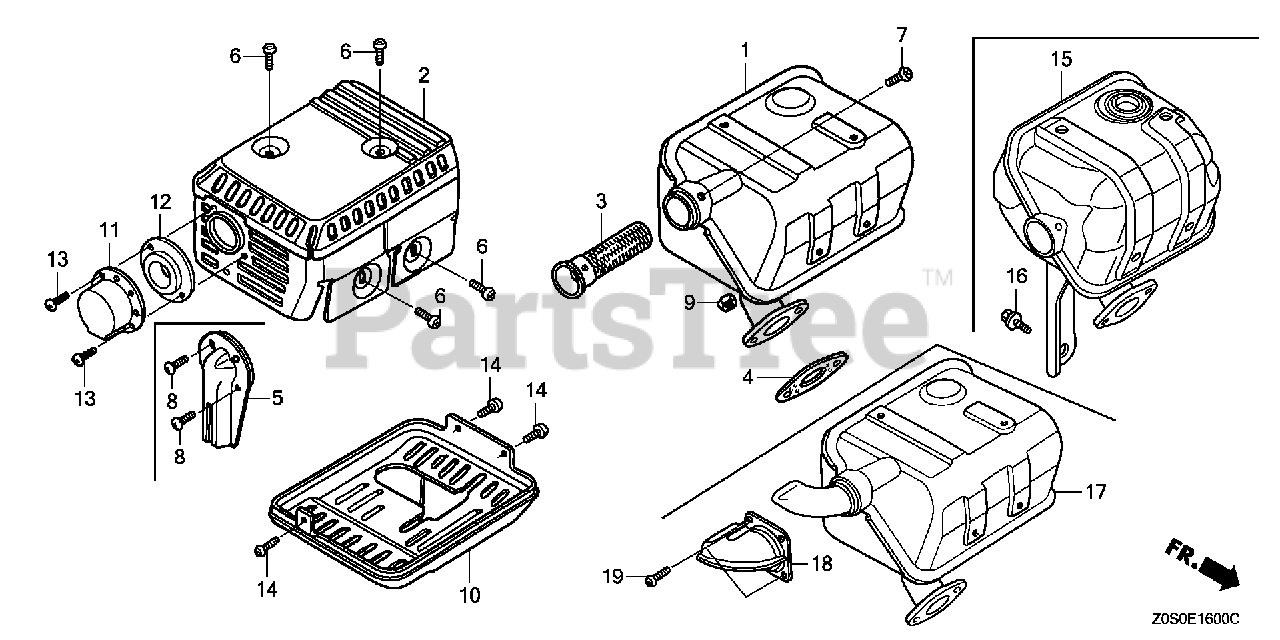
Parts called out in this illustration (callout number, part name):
1	MUFFLER (STD)
1	MUFFLER (ARRESTER)
2	PROTECTOR, MUFFLER (STD) (BLACK)
3	ARRESTER, SPARK
4	GASKET, MUFFLER
6	SCREW, TAPPING (5X8)
7	SCREW, TAPPING (4X6)
9	NUT, HEX. (8MM)
10	PROTECTOR (LOWER)
14	SCREW, TAPPING (4X6)
